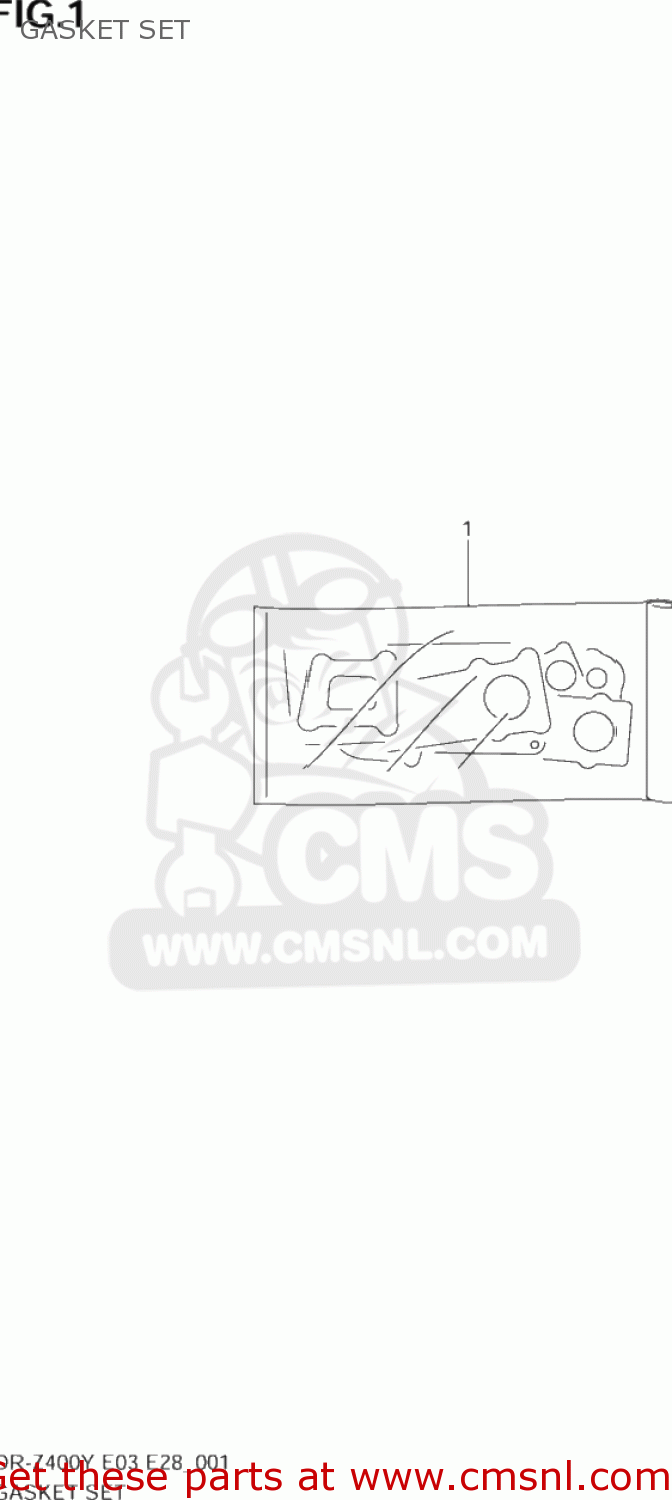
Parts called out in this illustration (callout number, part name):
1	GASKET SET (NAS)
2	GASKET,CYLINDER HEAD (NAS)
3	GASKET,CYL HEAD COVER (NAS)
4	GASKET,CYLINDER (NAS)
5	GASKET,CLUTCH COVER (NAS)
6	GASKET,MAGNETO COVER (NAS)
7	O RING,CLUTCH COVER OUTER
8	GASKET,TENSIONER ADJUSTER (NAS)
9	GASKET,EXHAUST PIPE
10	WASHER(10.6X25.5X2.3)
11	O RING(D:2.4,ID:11)
12	O RING(D:1.9,ID:13)
13	O RING(D:3.1,ID:16.8)
14	O RING(D:3.1,ID:32.7)
15	O RING(D:2.4,ID:52.6)
16	O-RING
